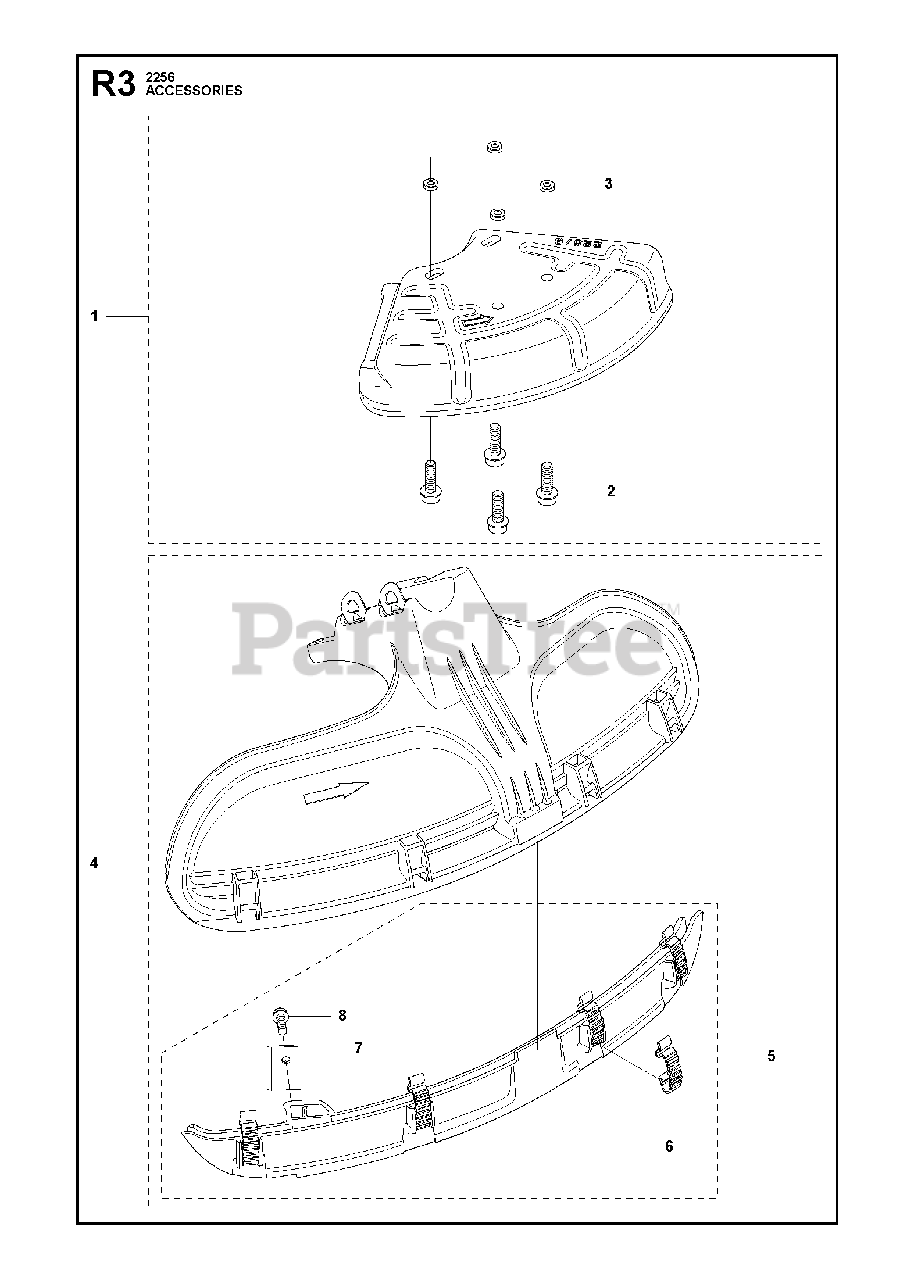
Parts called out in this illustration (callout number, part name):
1	BLADE GUARD
2	SCREW
3	LOCKING NUT
4	COMBINATION GUARD
6	BUCKLE
7	LINE CUTTER
8	SCREW
